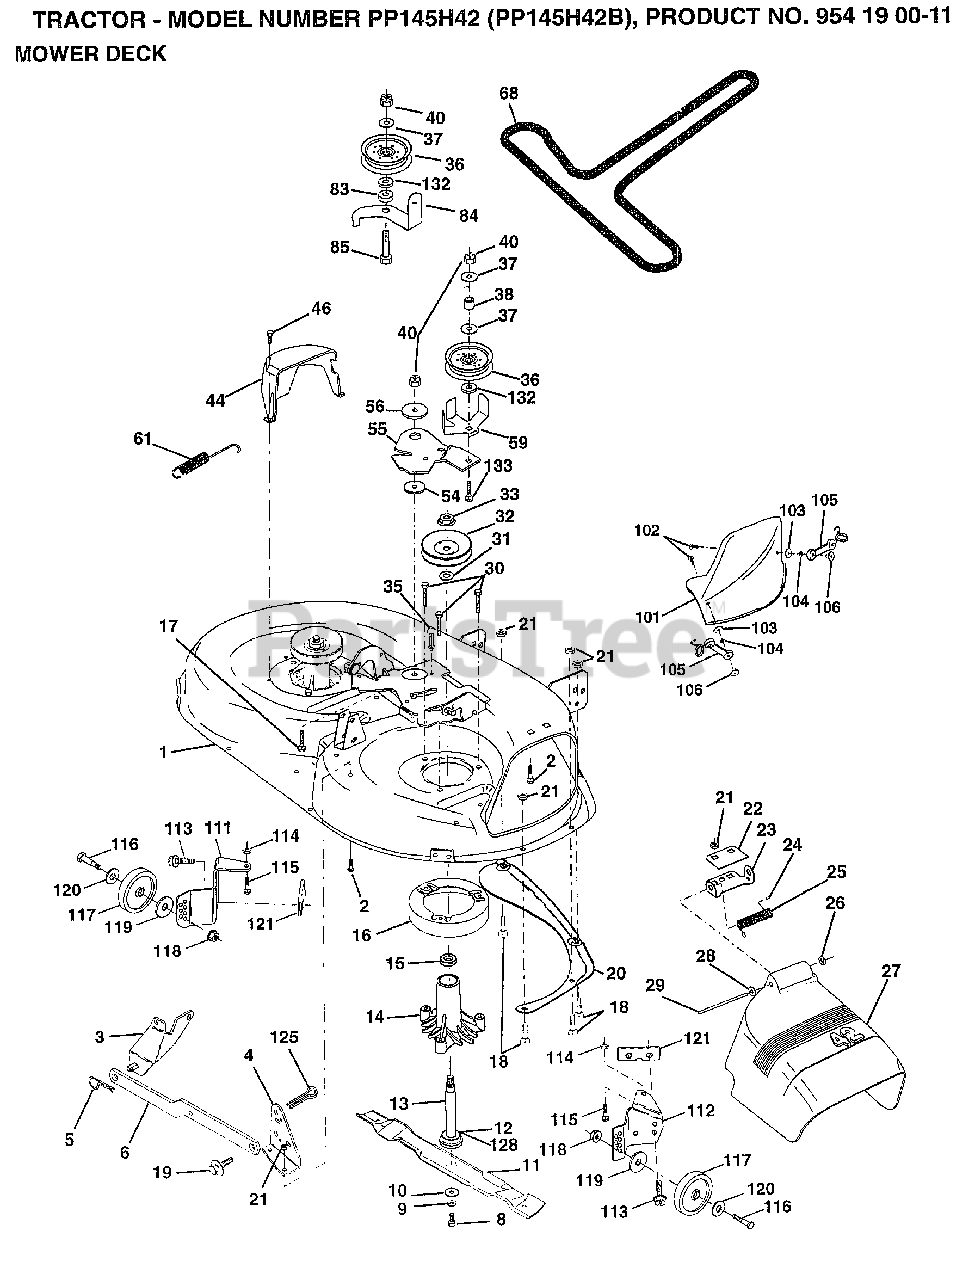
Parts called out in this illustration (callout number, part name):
1	DECK.WELD.42.
2	BOLT
3	BRKT ASM SWAY BAR
4	BRKT DECK SW BAR
8	BLADE BOLT
10	WASHER.HARD.BLADE
11	"BLADE.42"" MULCHER"
12	BEARING.BALL
14	HSG ASM MANDREL
15	BEARING
16	STRIPPER RND MWR
17	BOLT CARRIAGE
18	BOLT
19	BOLT SHD 5/16-18
22	STIFFENER BRKT
23	DEFLECTOR BRKT
24	CAP-SLEEVE LT
25	SPRING TORSION
26	NUT PUSH M
27	DEFLECTOR.SHIELD
28	WASHER
29	HINGE ROD
30	"SCREW-THD ROLL,WA"
31	WASHER
32	PULLEY.MANDREL.42
34	BOLT
35	XMAS TREE FASTNER
36	FLAT IDLER PULLEY
37	WASHER
44	GUARD MAND LH BLK
46	SCREW.1/4-20X5/8
54	HARDENED WASHER
56	SPACER RETAINER
59	GUARD IDLER TUV
61	SPRING.EXTENSION
68	BELT.V.T-PATH
83	WASHER
84	"KEEPER-BELT,FIXED"
85	BOLT RDHD 3/8-16
101	"COVER.MULCH.42"""
102	SCREW
103	WASHER #10
104	LOCKWASHER
105	LATCH ASSY.BAGGER
106	WELDNUT
111	BRACKET.GWHL.LH.
112	BRACKET.GWHL.RH.
113	SCREW
116	BOLT M
117	WHEEL.GAGE.BLK.PL
118	LOCKNUT
119	WASHER
120	WASHER
121	BRACKET.EXTRD.GWL
125	COTTER PIN
128	WASHER.FELT.
133	WASHER GT
